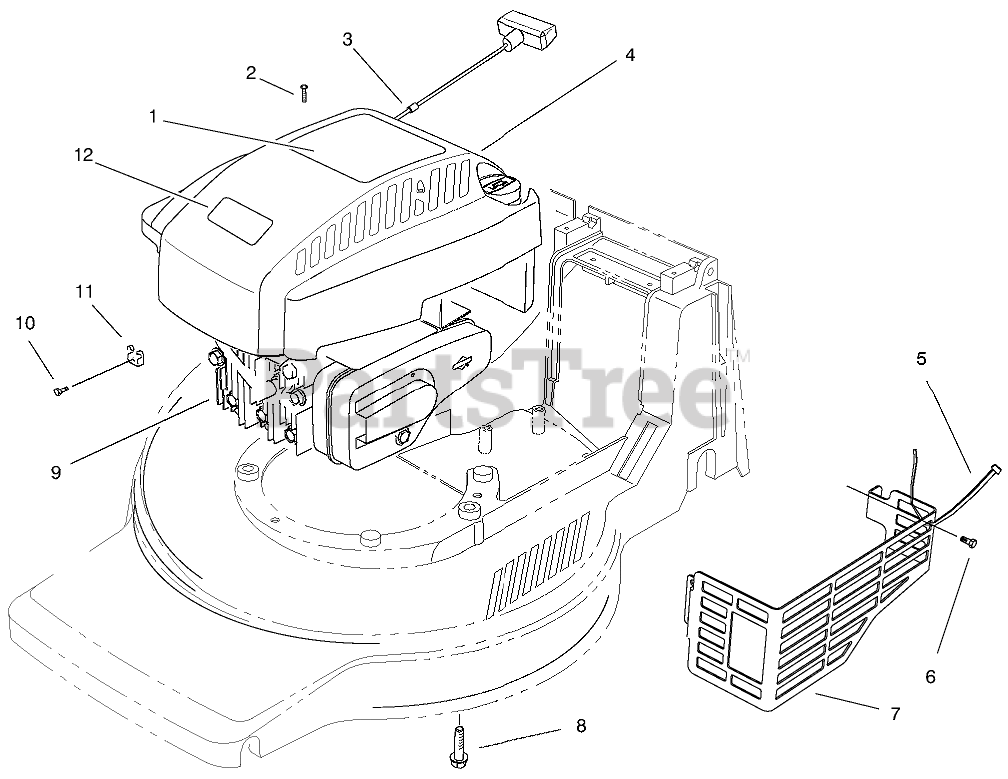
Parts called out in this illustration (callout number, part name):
1	SCREW-HWH
2	TIE-CABLE
3	CLAMP-CASING
4	SCREW-CLAMP
5	SCREW-HWH
6	SHIELD-MUFFLER
7	DECAL - RECOIL
9	STOP-ROPE
10	SHROUD-ENGINE
11	SCREW-PPH
12	PLATE-LOGO
